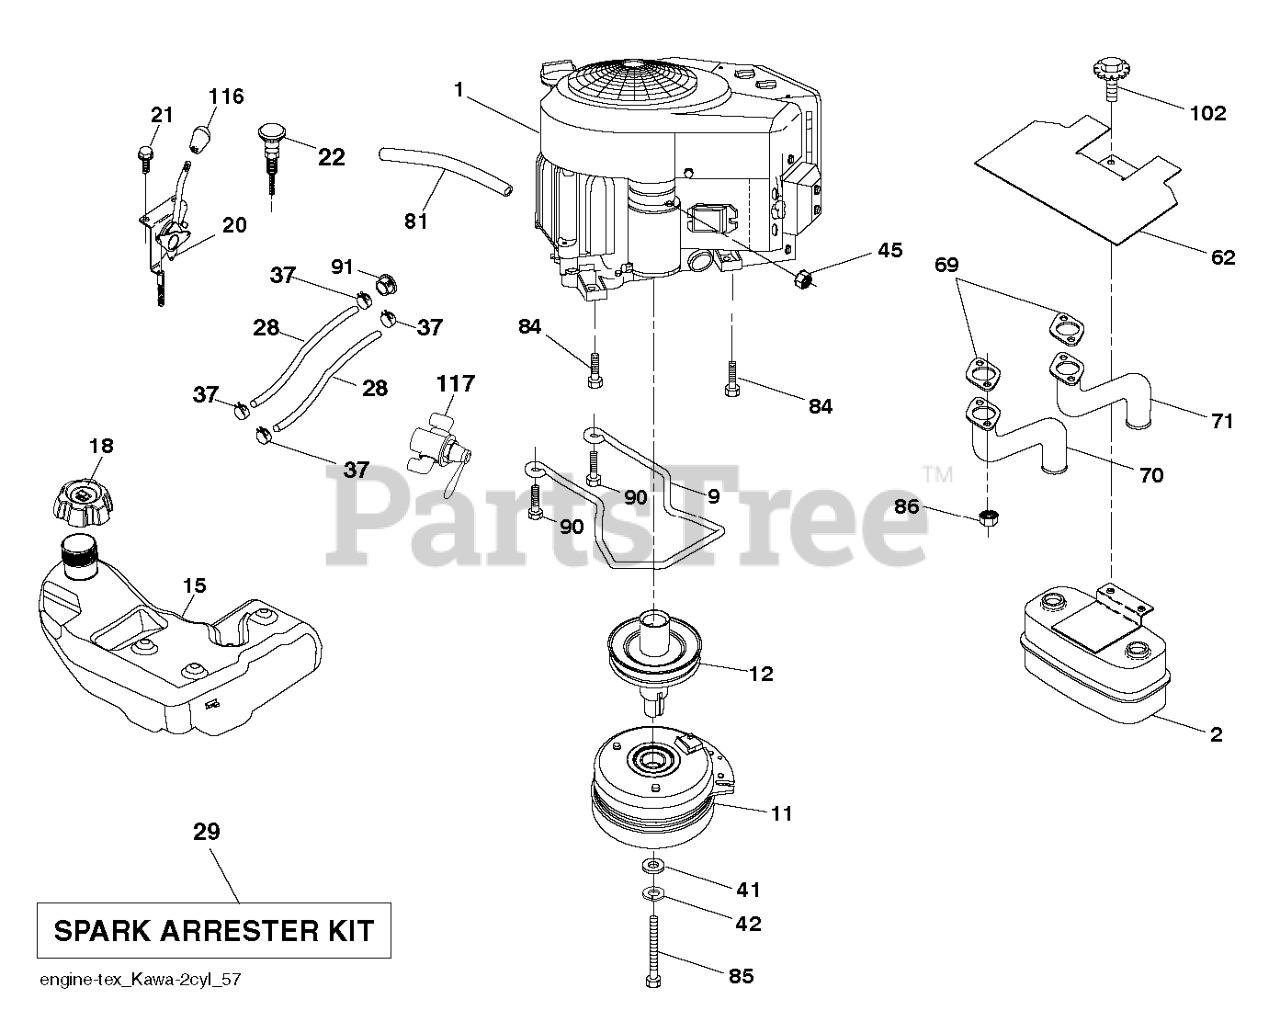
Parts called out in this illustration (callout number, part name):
2	MUFFLER.ASM.TWIN.MNTG.BRACKET
9	KEEPER.BELT.ENG.4.25"2.BLT.431
11	CLUTCH. 5.0 PD. 2.5 OFFSET
12	PULLEY.EXTENDED.SHAFT.GROUND
15	TANK.ASM.FUEL.4R.GAL.EPA.17
18	CAP ASSY FUEL 3" GRAY
18	FUEL CAP
20	CONTROL.THROTTLE.PRO.
21	SCREW.#10 X 0.750.BOS
22	CONTROL, CHOKE
28	HOSE 1/4" LOW PERMEATION FUEL
29	KIT.SPARK ARRESTOR 794945 B&S
37	HOSE CLAMP
42	WASHER 7/16 LOCK
45	NUT
62	SHIELD.HEAT.MUFFLER
70	TUBE.EXHAUST.LH.FR961/FR730
71	TUBE.EXHAUST.RH.FR961/FR730
81	TUBE, DRAIN OIL ASM.
84	SCREW 3/8-16X1
85	BOLT.HEX.7/16-20X5.GR5.GREEN
86	NUT.HEX.FLANGE.TOPLOCK
90	SCREW 3/8-16X1
91	BUSHING.1.375OD
102	SCREW
116	KNOB - SHIFT
117	VALVE FUEL RESERVE
